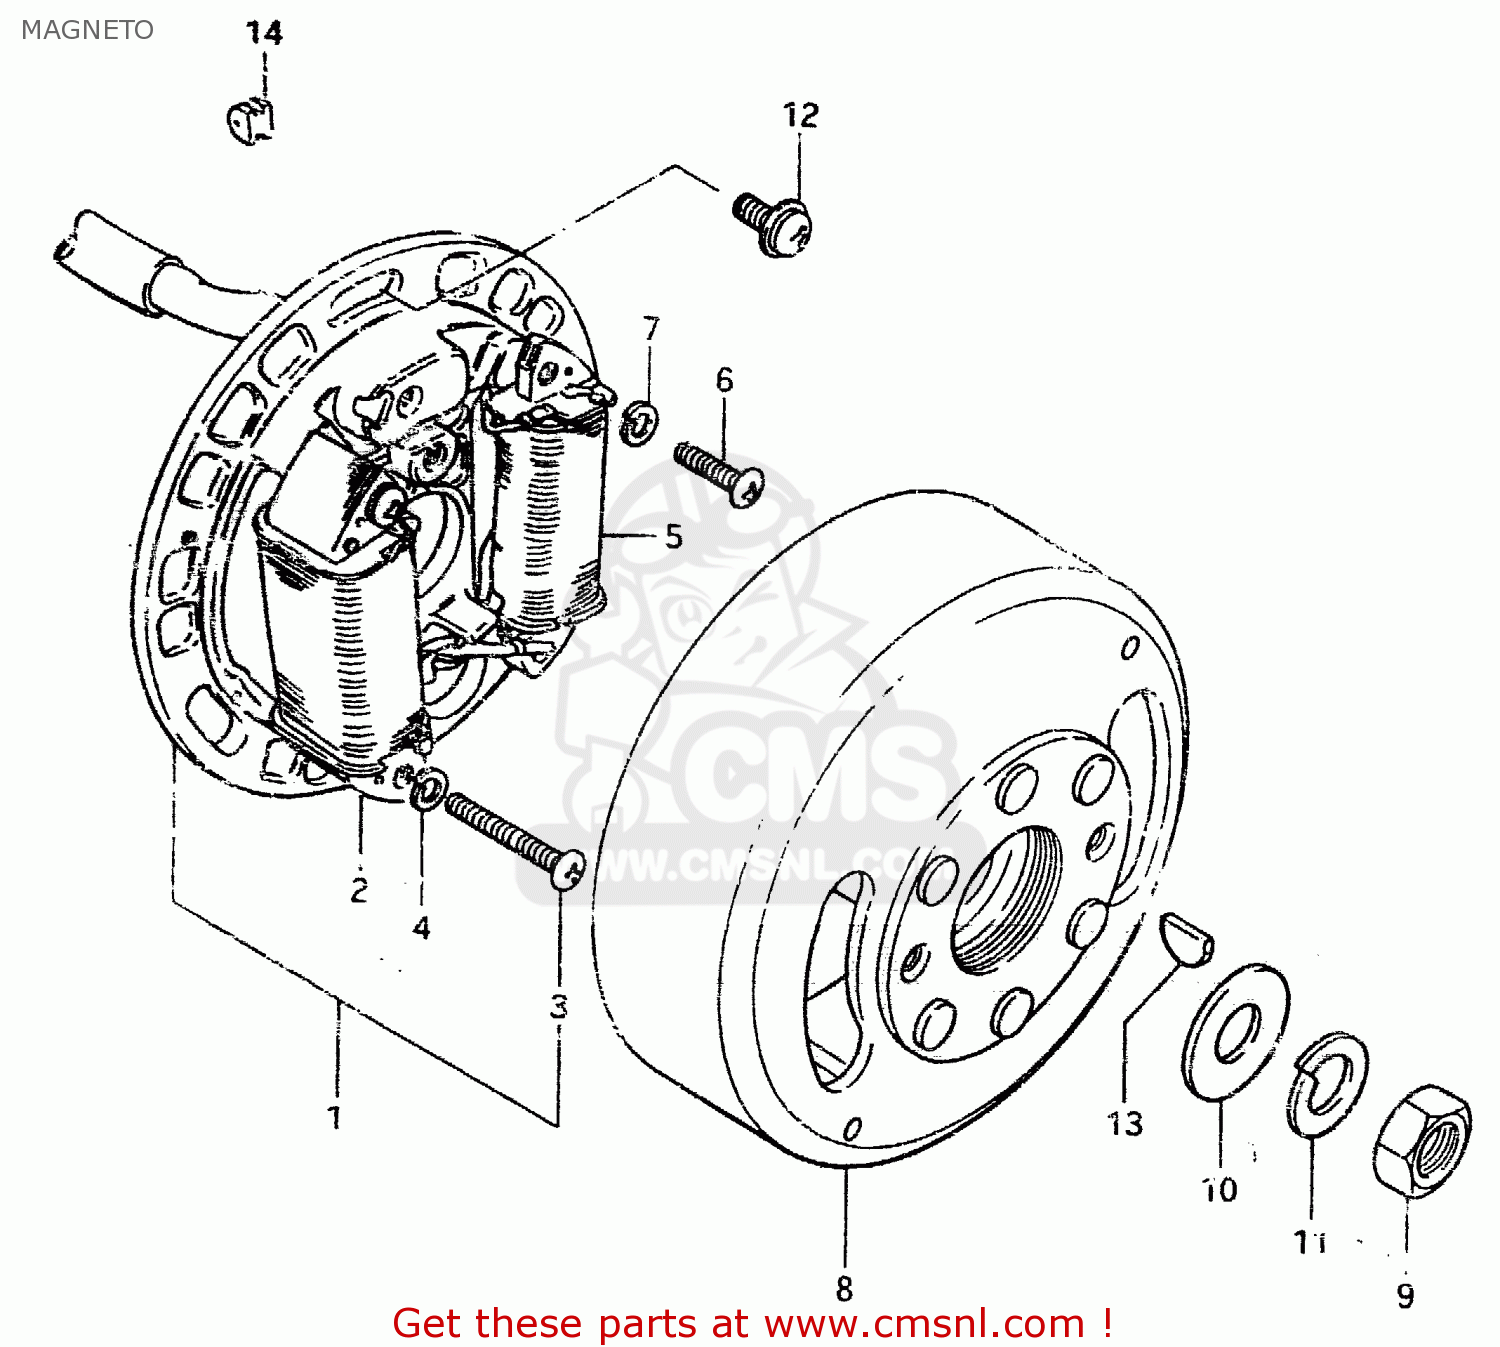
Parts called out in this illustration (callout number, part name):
1	STATOR ASSY
2	COIL,LIGHTING
3	SCREW (4X30)
4	LOCK WASHER
5	COIL,PRIMARY
6	SCREW
7	LOCK WASHER
8	ROTOR
9	NUT (10MM)
10	WASHER
11	LOCK WASHER
12	SCREW(5X14)
13	KEY
14	GROMMET,NEUTRAL LEAD WIRE
